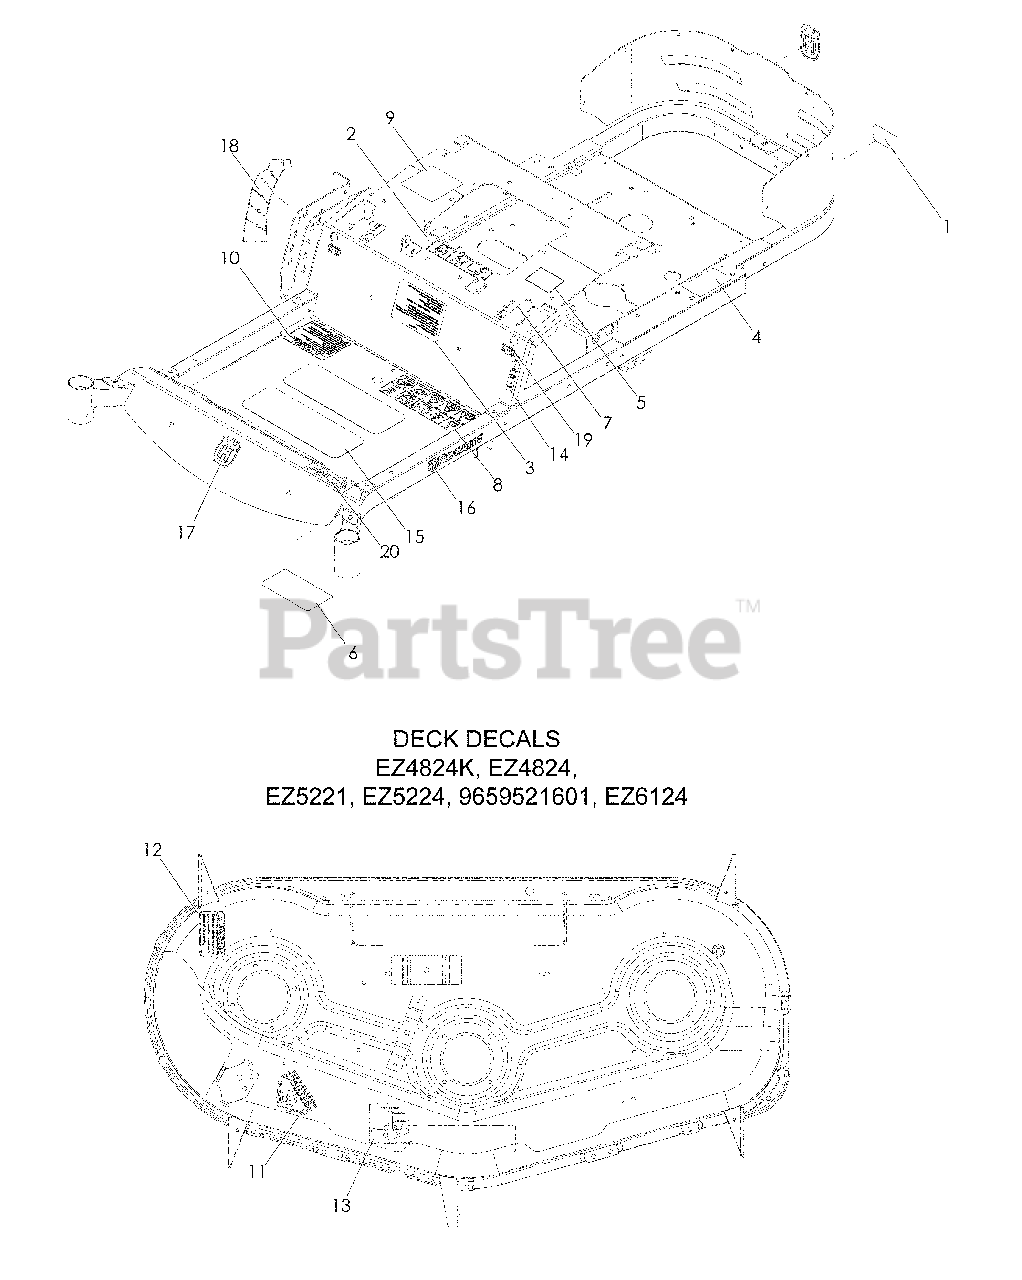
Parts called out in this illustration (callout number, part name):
1	DECAL, PROP 65
2	DECAL, BATTERY WARNING
3	DECAL, START
4	DECAL, DO NOT TOW
5	DECAL, EXIT MOWER
6	DECAL, SERVICE
7	DECAL, MOTION CONTROL
8	DECAL, SAFETY WARN
9	DECAL, RESPONSIBILITY
10	DECAL, WARNING
11	DECAL, CPSC
12	DECAL, WARNING
13	DECAL, BELT ROUTING
14	DECAL, PARK BRAKE
15	ABRASIVE PAD
16	DECAL, HUSQVARNA
17	DECAL, CROWN H
18	DECAL, HEIGHT
19	DECAL, FST
20	DECAL, EZ4824
